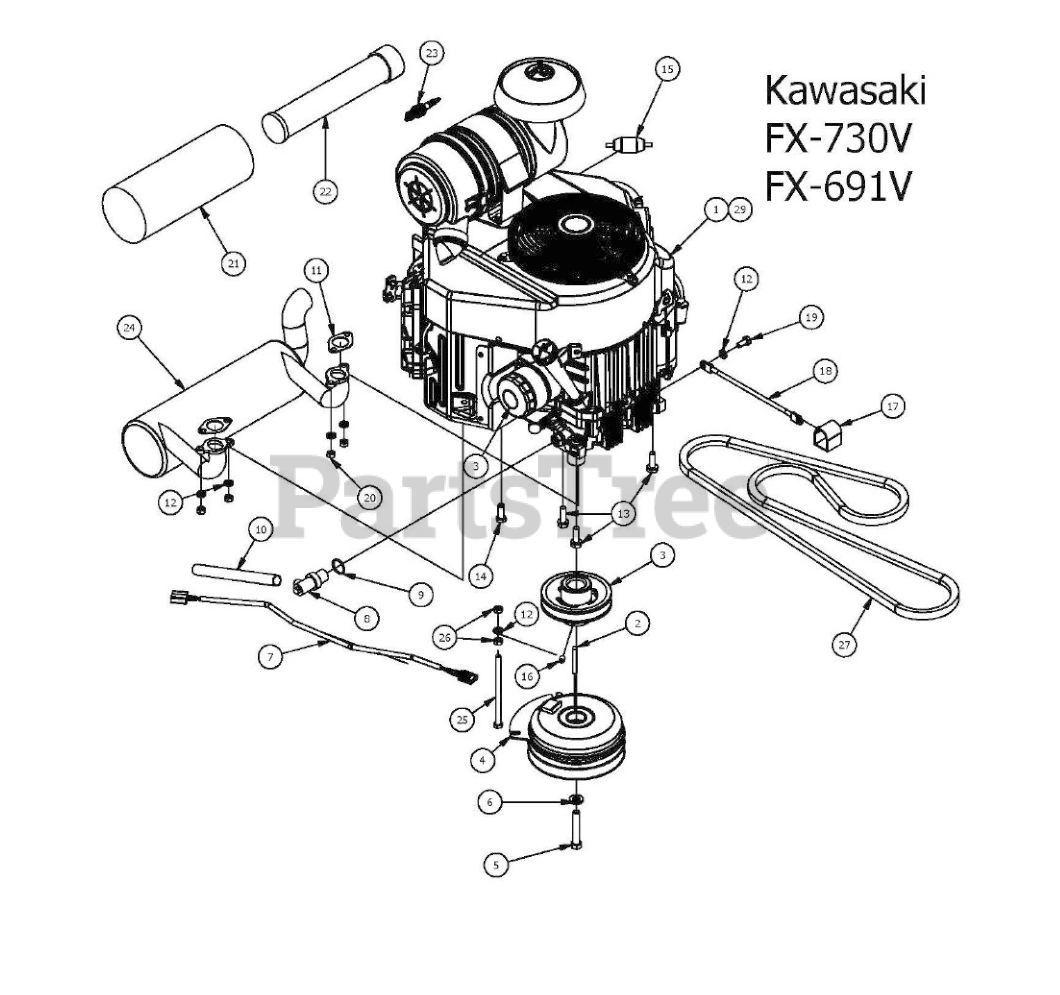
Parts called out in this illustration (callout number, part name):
2	1/4 x 2 Square key Stock
3	4 3/4 Motor Pulley
4	Clutch Assembly
5	7/16" x 2 1/2" Hex Bolt
6	7/16" Lock Washer
7	Clutch Pigtail
10	1/2 Clear Braded Hose Priced/Foot
11	Exhaust Gasket
12	5/16" Lock Washer
13	3/8 x 1 1/8 bolt
14	3/8" x 1" Hex Bolt
15	Universal Inline Fuel Filter
16	5/16 Set Screw
17	Black Boot For Ground Cable
18	Ground Cable
19	M8x1.20x20MM Hex head bolt
20	M8-1.25 Zinc Nut
21	Canister Air Filter- Outer
22	Canister Air Filter- Inner
23	Spark Plug- Kawasaki
24	Exhaust-2015 Stand On
25	5/16-18 x 5-1/2 GR 5 Hex Bolt
28	Kawasaki Oil Filter
